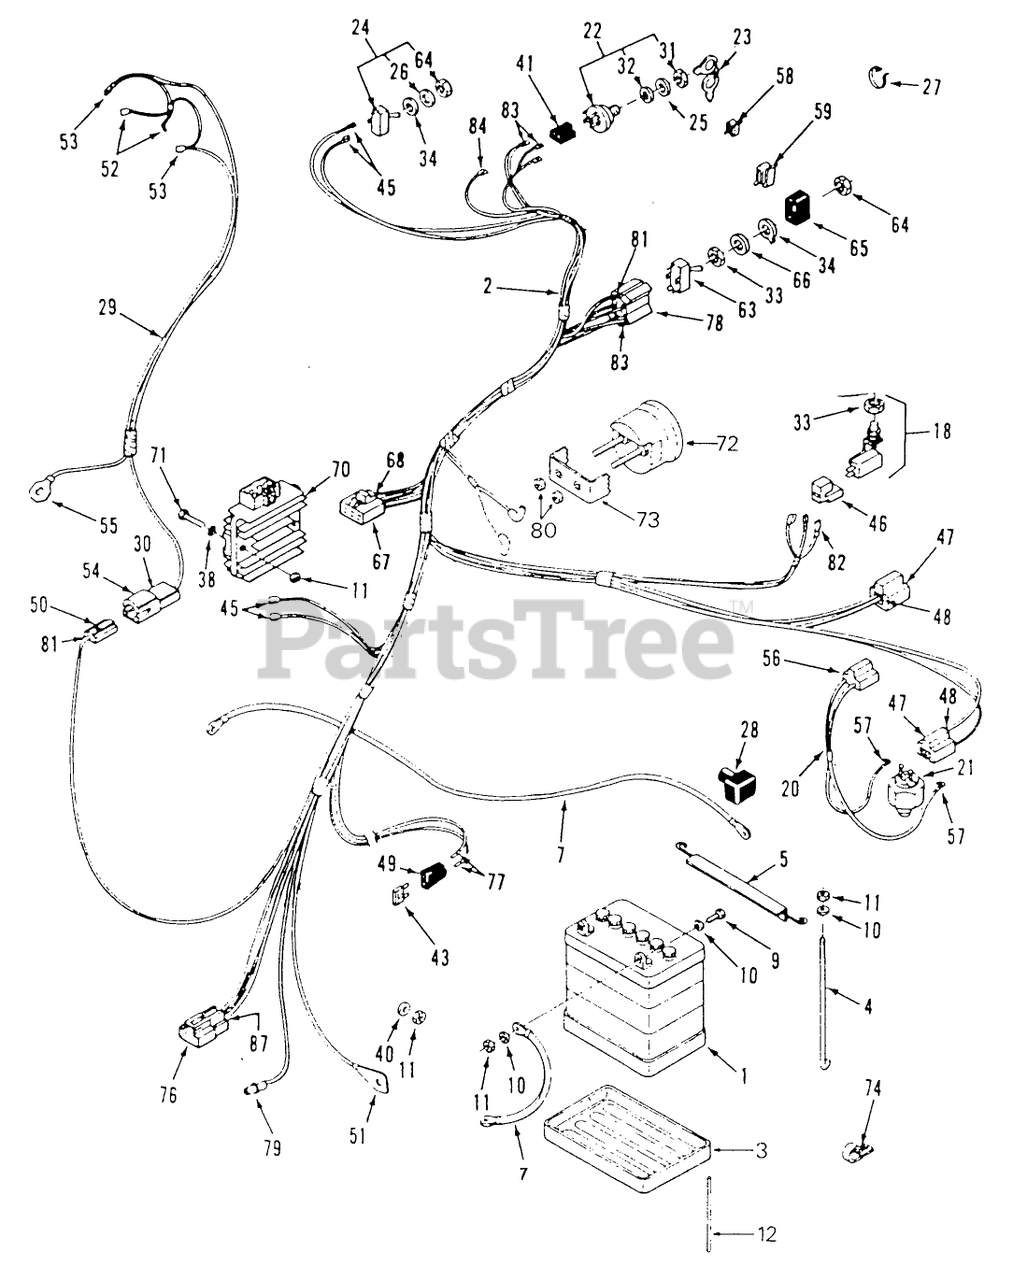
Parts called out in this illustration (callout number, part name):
3	TRAY-BATTERY
5	HOLDDOWN-BATTERY
7	WIRE - 14" BLACK
12	TUBE-BATTERY DRAIN
20	ASSY WIRING HARNESS
21	SWITCH (N.C.-TRANS)
24	SWITCH-LIGHTS
26	Washer
29	HARNESS-HEADLIGHT
34	TAB-WASHER
43	FUSE-BLADE, 15 AMP
45	Connector .250 x .032
46	CONNECTOR BODY
47	CONNECTOR BODY
48	TERMINAL-LONG MALE
51	Ring Terminal
53	Female Dbl. Crimp Terminal (part of item 29) 211
54	Connector Part of 5
55	Ring Terminal (part of item 2)
56	CONNECTOR BODY *B
57	TERMINAL-TAB RCPT
58	CLIP
64	*DISC**
65	COVER-PTO SWITCH
66	WASHER-FLAT
72	GAUGE-HOURMETER
73	BRKT-GAUGE MOUNTING
74	CLAMP
77	Fuse Holder Term. (1 used on 212) 208, 211
78	CONNECTOR 5 WAY
82	OBTAIN LOCALLY
84	Belt Guide-Bottom 308 Only
